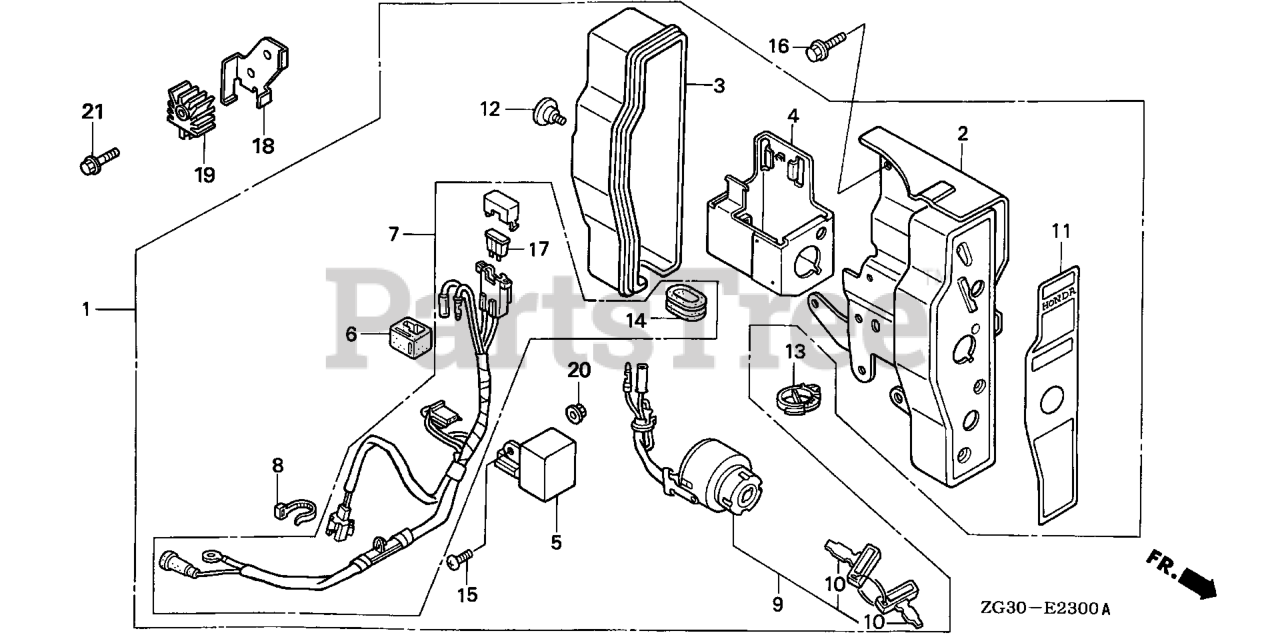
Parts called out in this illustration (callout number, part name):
1	BOX ASSY., CONTROL
2	PANEL, CONTROL *NH116M* (URBAN SILVER METALLIC)
3	CASE, CONTROL
4	BRACKET, CASE MOUNTING
5	RECTIFIER, SILICON
6	SUSPENSION, CONNECTOR
7	WIRE HARNESS ASSY., CONTROL
8	BAND
9	SWITCH ASSY., COMBINATION
10	KEY
11	MARK, CONTROL BOX (EXTERNAL)
12	SCREW, SPECIAL (6X12)
13	CLIP, WIRE HARNESS
14	GROMMET, WIRE HARNESS
15	SCREW, PAN (6X12)
16	BOLT, FLANGE (6X16) Use from Engine SN 2056820.
17	FUSE, BLADE (15A)
